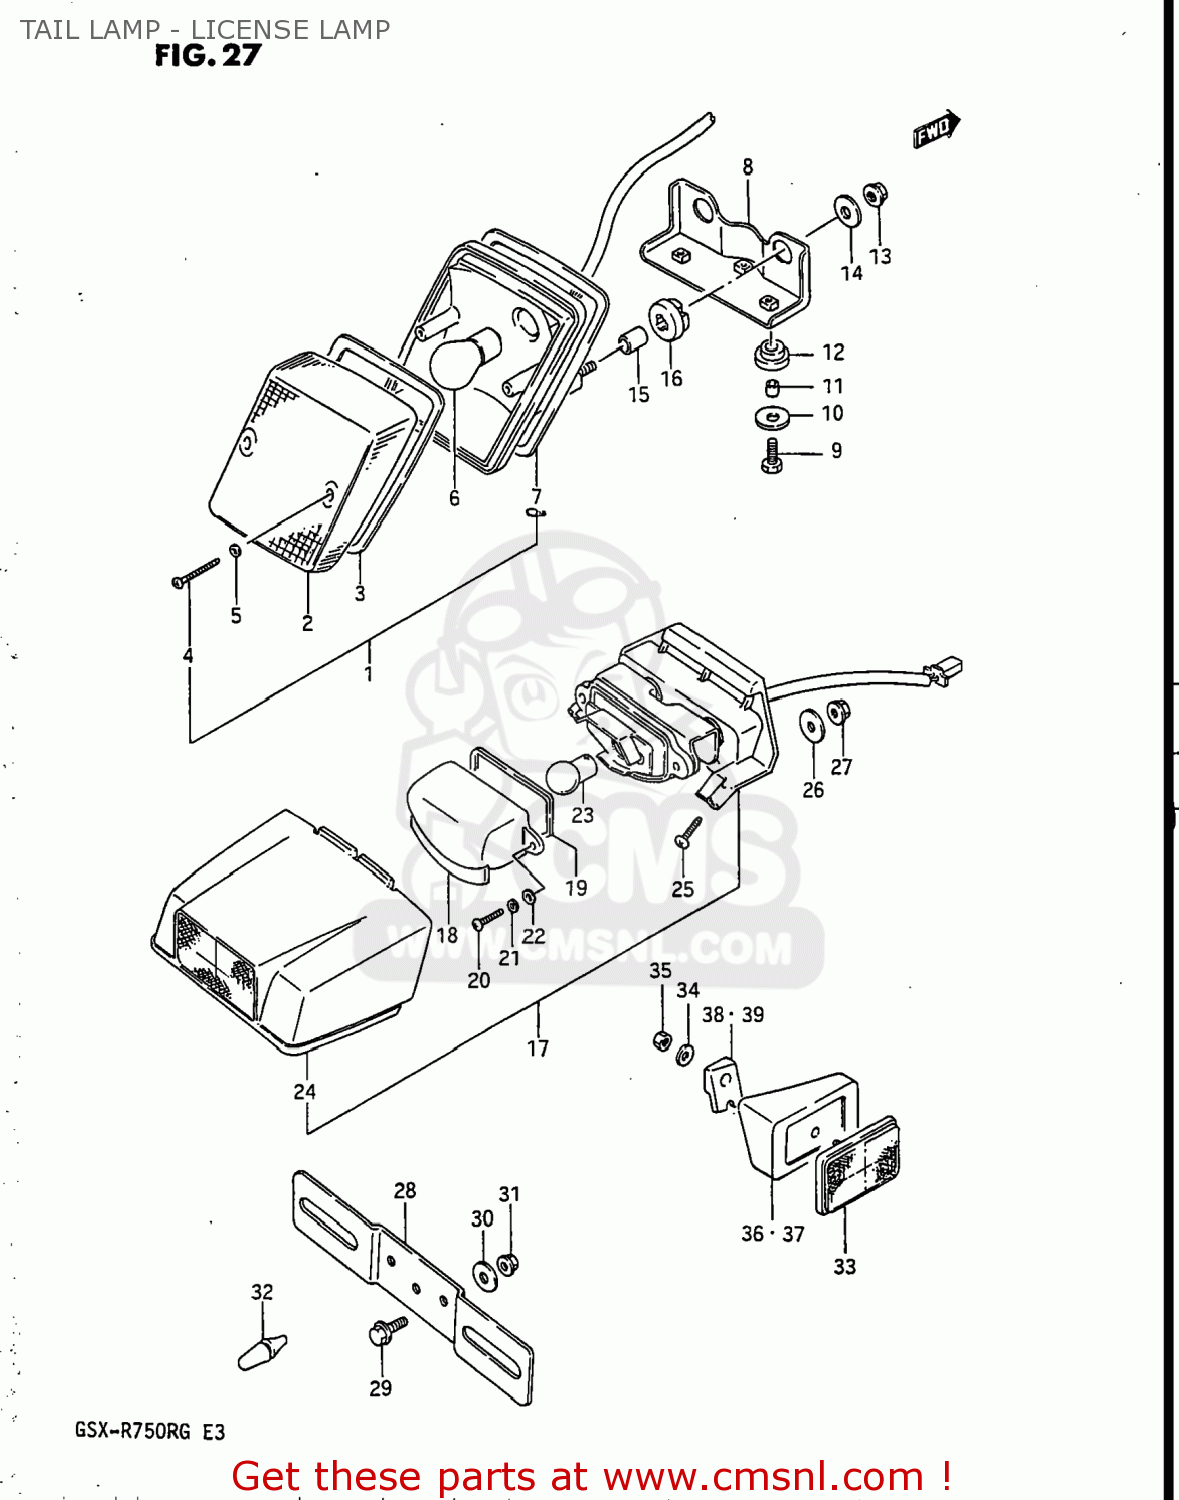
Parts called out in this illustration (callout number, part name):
1	LAMP ASSEMBLY,REAR COMBINATION
2	LENS,RR COMBI
3	GASKET,REAR COMBINATION LAMP
4	SCREW TAPP.
5	GASKET (NAS)
6	BULB(12V23/8W,TOKAI DENSO)
7	GASKET
8	BRACKET,REAR COMBINATION LAMP
9	BOLT,M6X1X20
10	WASHER
11	SPACER (6.1X9X7.5)
12	CUSHION
13	NUT
14	WASHER
15	SPACER (6.4X9X10.5)
16	CUSHION
17	LAMP ASSY,LICENSE
18	LENS,LICENSE LAMP
19	GASKET,LICESE LAMP (NAS)
20	SCREW
21	WASHER,LOCK 4M
22	WASHER 4MM
23	BULB
24	COVER,LICENSE LAMP
25	SCREW
26	WASHER (5.5X20X1.2)
27	NUT
28	BRACKET,LICENSE PLATE
29	BOLT
30	WASHER
31	NUT
32	CUSHION
33	REFLEX REFLECTOR,REAR SI
34	WASHER(5.2X16X1)
35	NUT ,5MM
36	SPACER
37	SPACER
38	WASHER
39	SPACER, INNER LH
